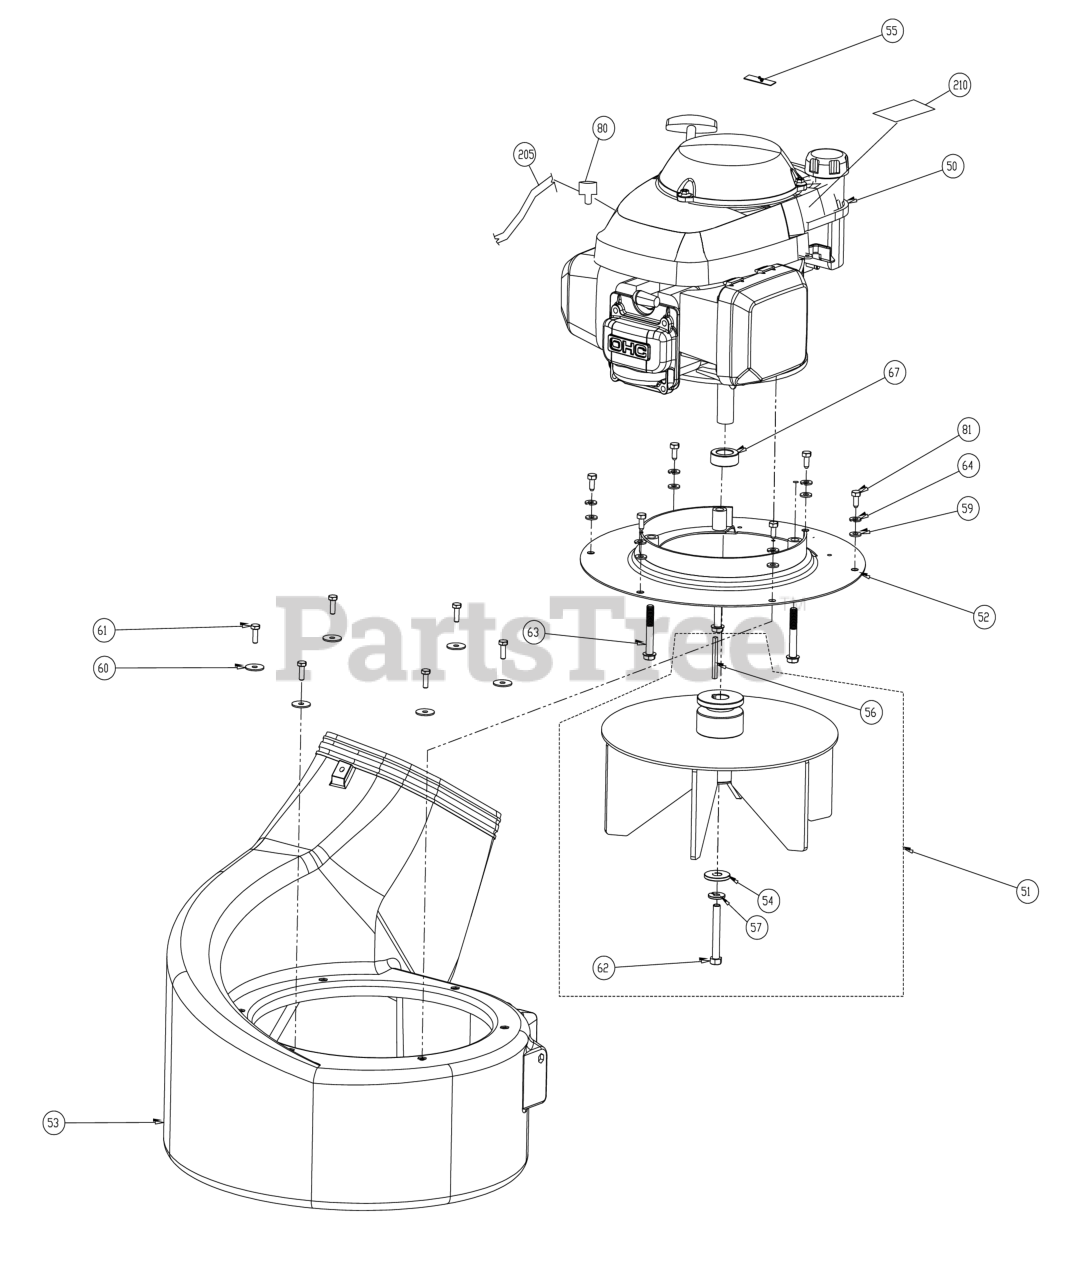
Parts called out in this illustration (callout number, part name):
50	ENGINE B&S PRO SERIES 875 ELEC START
51	IMPELLER ASSEMBLY SP MV VAC
52	PLATE TOP WA SP VAC
53	HOUSING WITH PVC LINER MV
54	WASHER 1.5 OD X .453 ID X .25 THK
56	KEY 3/16" SQ X 2 1/8"
57	WASHER LOCK 3/8" S/T MED
59	WASHER 1/4"SAE9/32"X5/8"X1/16"
60	WASHER FLAT FENDER 1/4"
61	SCREWCAP 1/4"-20X3/4" HCS ZP
62	SCREWCAP 3/8"-24 X 2 3/4"GR.8
63	SCREWCAP 3/8"-16X2 1/2" TAPTITE
64	WASHER LOCK 1/4" S/T MED
67	SPACER 1.50 OD X .890 ID X .50 THK
80	TERMINAL 18-14 BLUE T-TAP
81	SCREWCAP 1/4"-20 X 5/8" GR 5
205	SEE: 840275
210	LABEL HOT ENGINE
